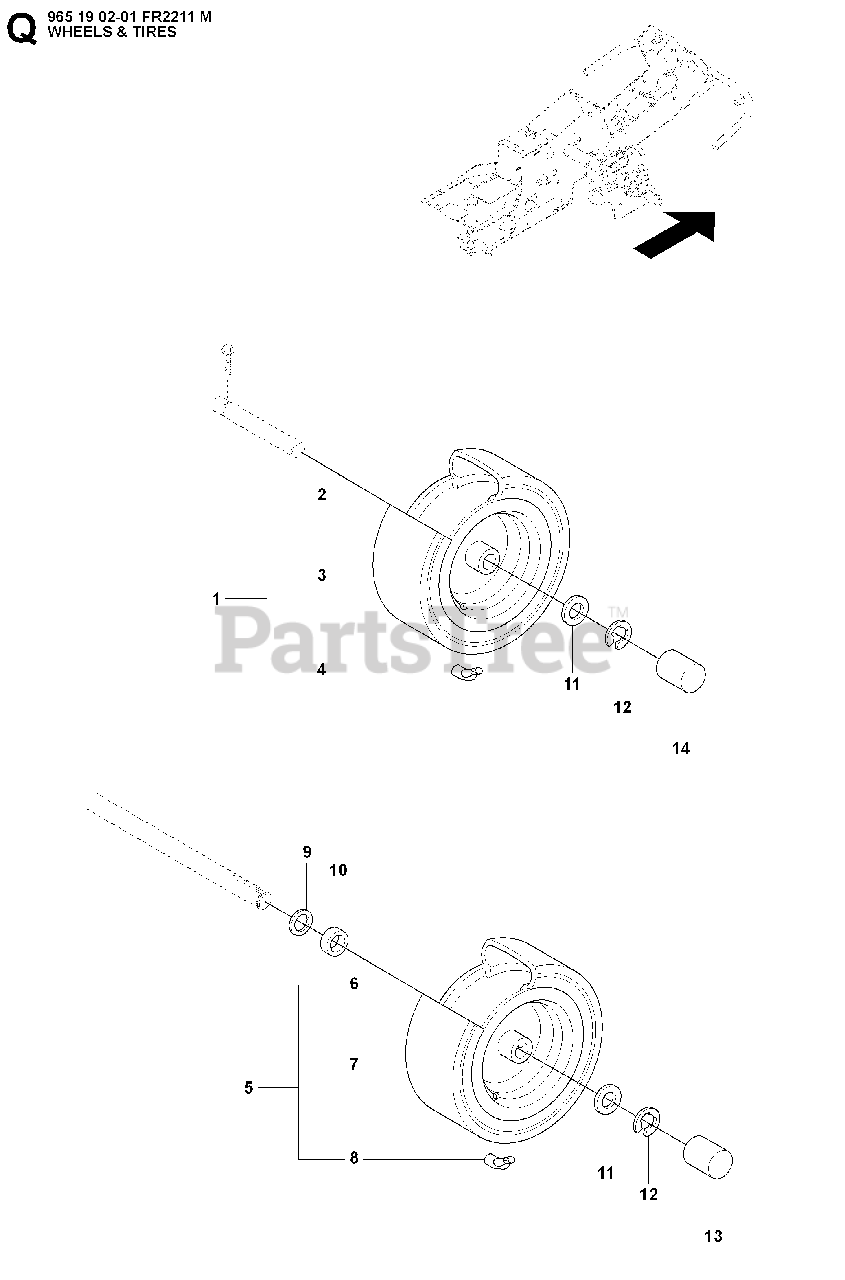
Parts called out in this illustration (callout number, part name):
6	RP RIM
12	RETAINING RING
13	DUST CAP
